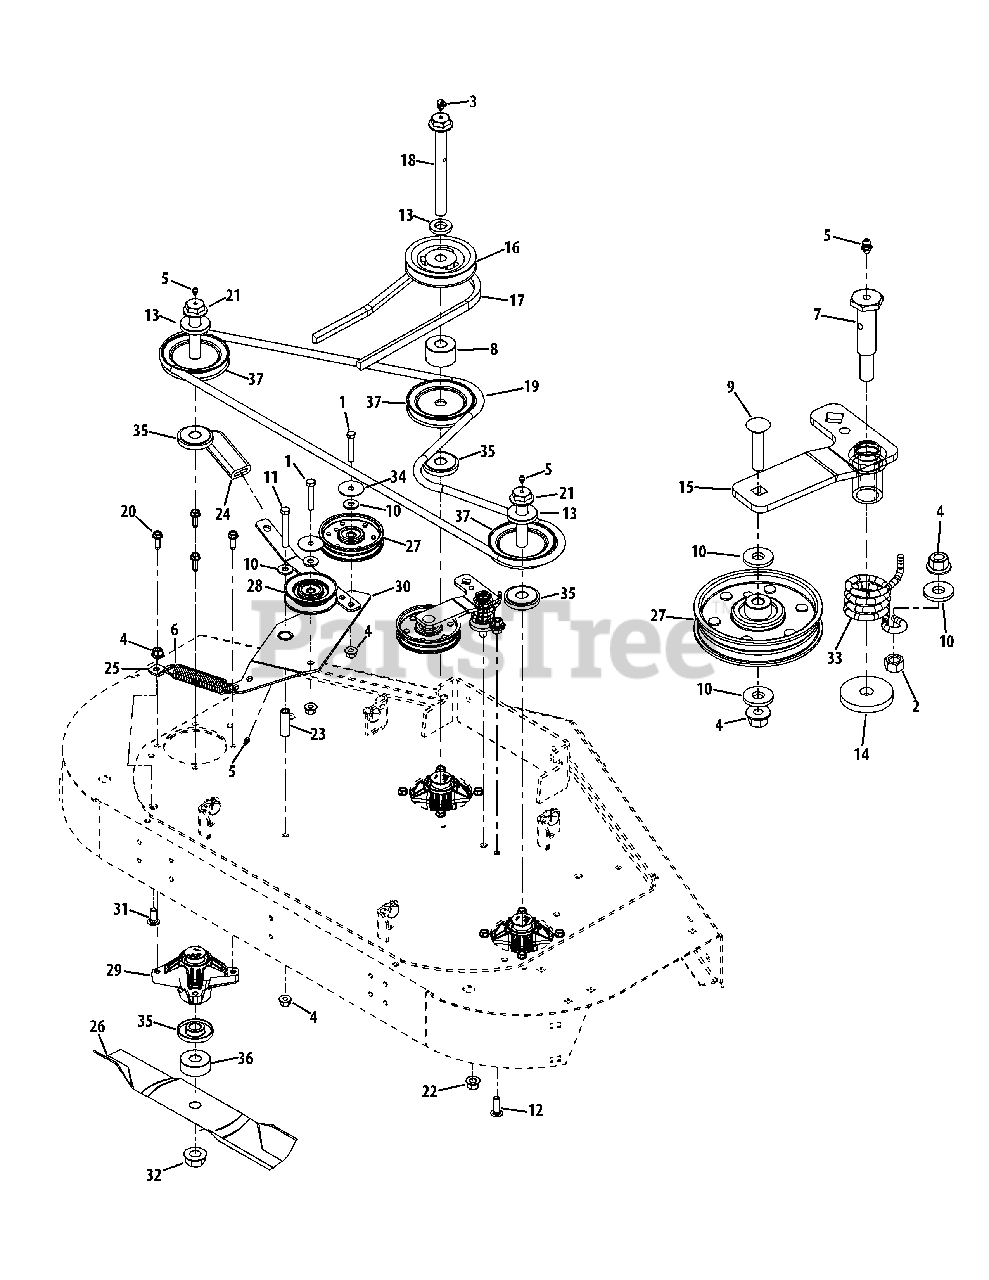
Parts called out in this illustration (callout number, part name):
1	Hex Screw, 3/8-16 x 2.00
2	Nut, 3/8-16
3	Grease Fitting, 1/4-28 x .788
4	Flange Counterlock Nut, 3/8-16
5	Grease Fitting, 1/4-28
6	Extension Spring, 1.00 x 5.00 x .125
7	Shoulder Bolt, .625 x 1.95
8	Spacer, .760 x 2.00 x 1.27
9	Carriage Bolt, 3/8-18 x 1.75
10	Washer, .406 x 1.00 x .105
11	Hex Screw, 3/8-16 x 3.00
12	Carriage Bolt, 3/8-16 x 1.25
13	Spacer, 2.0 x .75 ID x .31
14	Washer, .438 x 1.75 x .250
15	Idler Arm Assembly
15	Sleeve Bearing, .638 x .753 x .615
17	V-Belt, PTO
18	Hex Screw, 3/4-16 x 7.7
19	V-Belt, Deck
20	Hex Flange Screw, 5/16-18 x 1.00
21	Hex Flange Screw, 3/4-16 x 5.625
22	Flange Counterlock Nut, 7/16-14
23	Spacer, .390 x .625 x 1.88
24	Flat Grip, 1.0 x 3.2 x .25
25	Spring Mount Bracket
26	Blade, Hi-Lift, 19.0
27	Idler Pulley, Flat
28	Idler Pulley, V
29	Spindle Assembly
30	Double Idler
31	Carriage Bolt, 3/8-16 x 1.00
32	Flange Lock Nut, 3/4-16
33	Torsion Spring
34	Washer, .406 x 1.92 x .060
35	Deck Spindle Spacer
36	Spacer, .760 x 2.000 x .790
